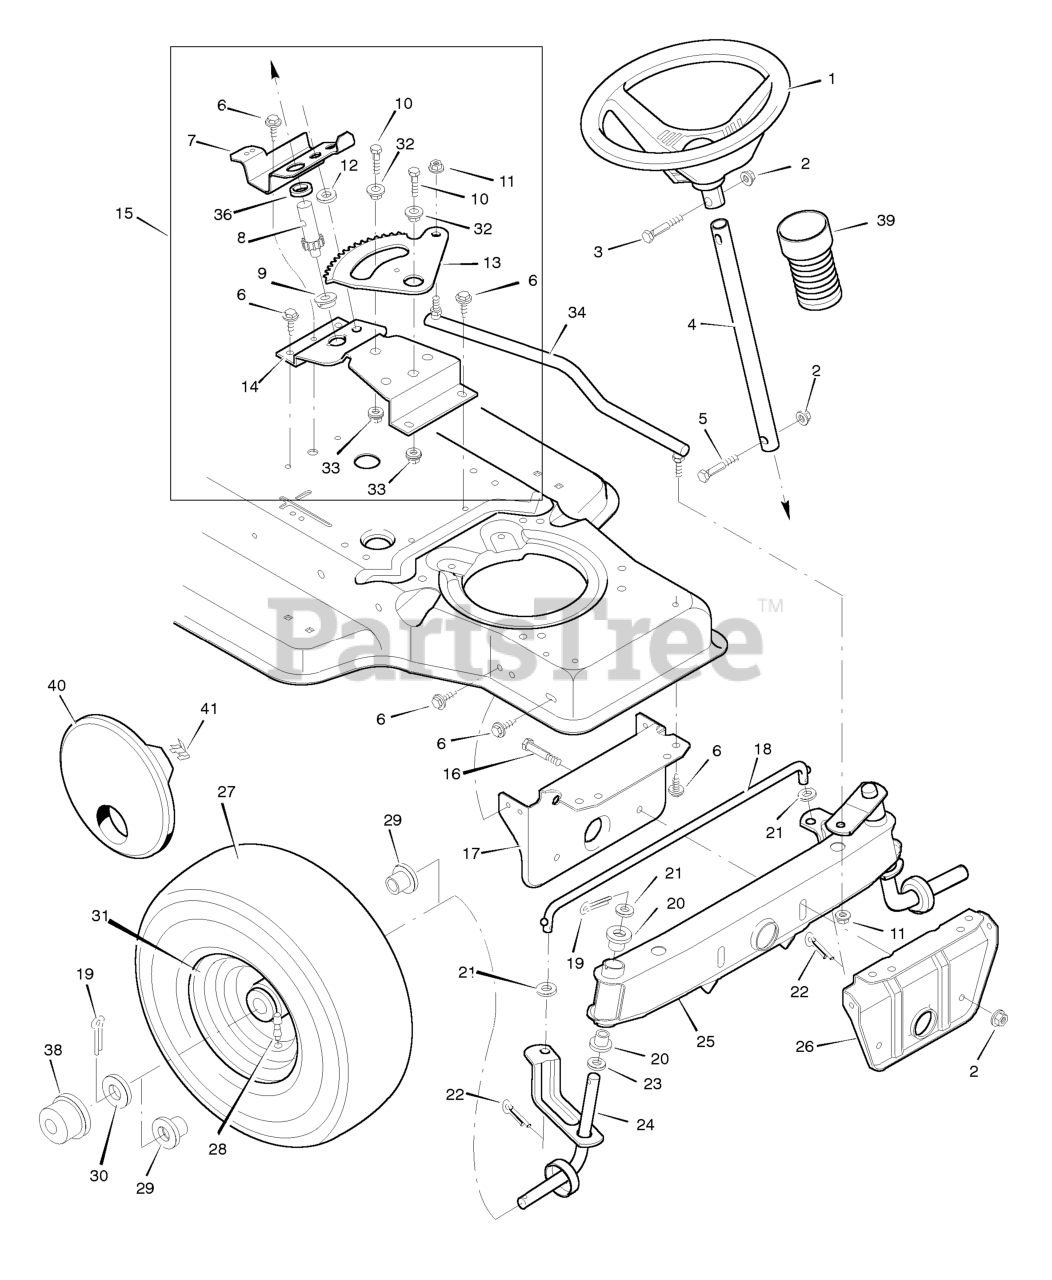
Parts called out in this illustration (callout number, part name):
1	Wheel, Steering
2	Nut, Hex
3	Bolt, Hex
4	Post, Steering
5	Bolt, Hex
7	Bracket, Sector
8	Gear, Pinion
9	Bearing
10	CAPSCREW, Hex Head, 5/16-18 x 1
11	Locknut, Flange
13	Gear, Sector
14	Bracket, Sector
15	Kit, Steering Gear
16	Bolt, Hex
17	Support, Rear Axle
18	Rod, Tie
19	Pin, Cotter
20	Bearing
22	Pin, Cotter
24	Spindle Assembly, Right
25	Spindle Assembly, Axle & Left
26	Support, Front Axle
27	Tire *
28	Stem, Valve
29	Bearing, Wheel
31	Wheel & Tire Assembly
32	Bearing
33	Locknut, Flange
34	Link, Drag
36	Spacer, Pinion Gear
38	Hub Cap
39	Bellows
40	Disc, Wheel
41	Clip, Retainer
